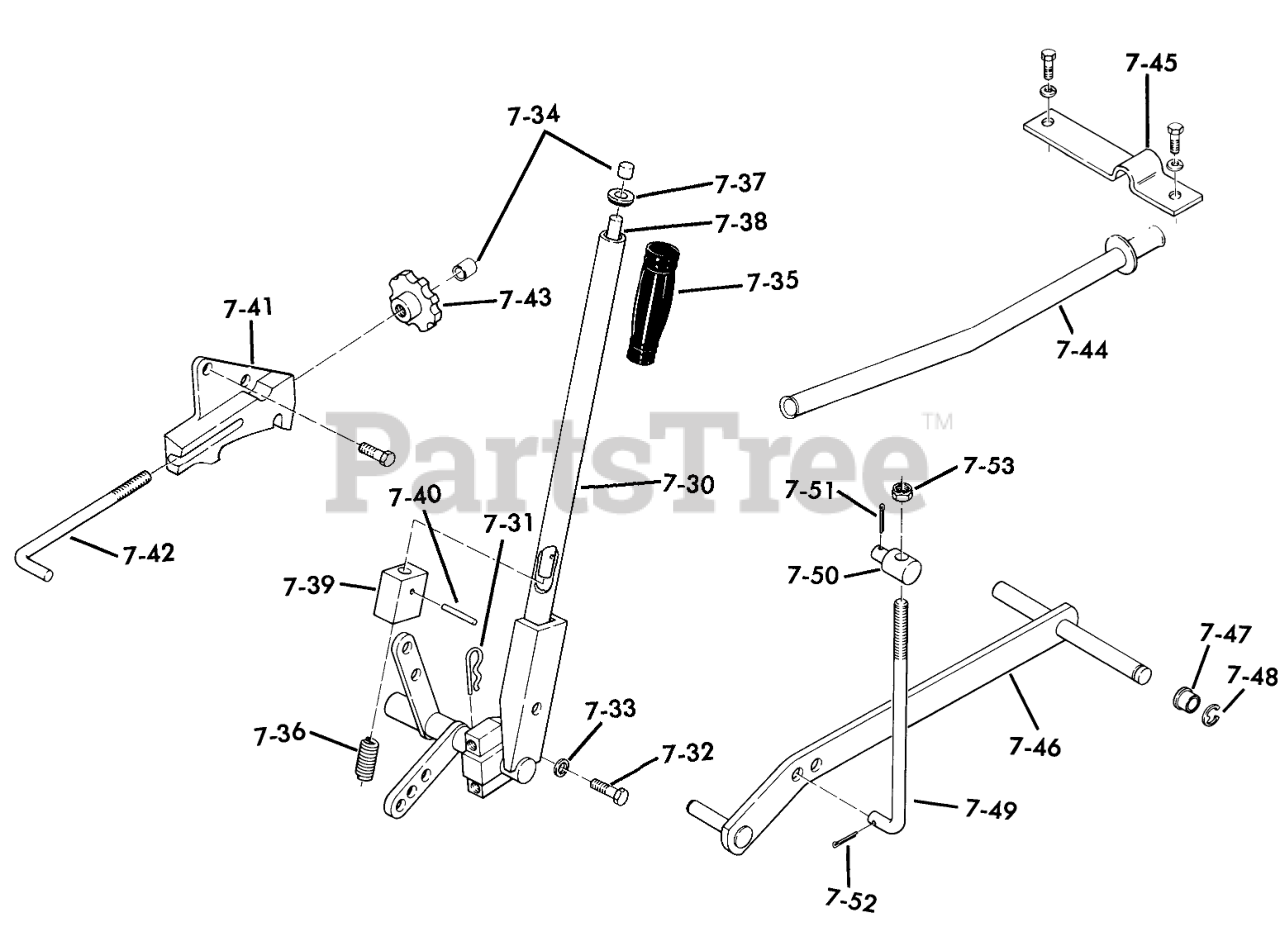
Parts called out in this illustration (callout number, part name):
7-30	Lift Lever
7-31	Hairpin
7-32	H H C S
7-33	Lockwasher
7-34	CAP-ROD, PLUNGER
7-35	HANDGRIP
7-36	SPRING-COMPRESSION
7-37	Guide-Rod
7-38	PLUNGER ROD
7-39	LOWER PLUNGER R
7-40	Roll Pin
7-41	Quadrant
7-41	Bolt
7-42	ROD-LIFT CONTROL
7-43	KNOB-LIFT CONTROL
7-44	Clamp-Conduit
7-45	Clamp-Tube
7-46	ASSY LIFT BAR R
7-47	BUSHING
7-48	E Ring
7-49	ROD-LIFT
7-50	TRUNNION-LIFT
7-51	Hairpin
7-52	Cotter Pin
7-53	NUT
